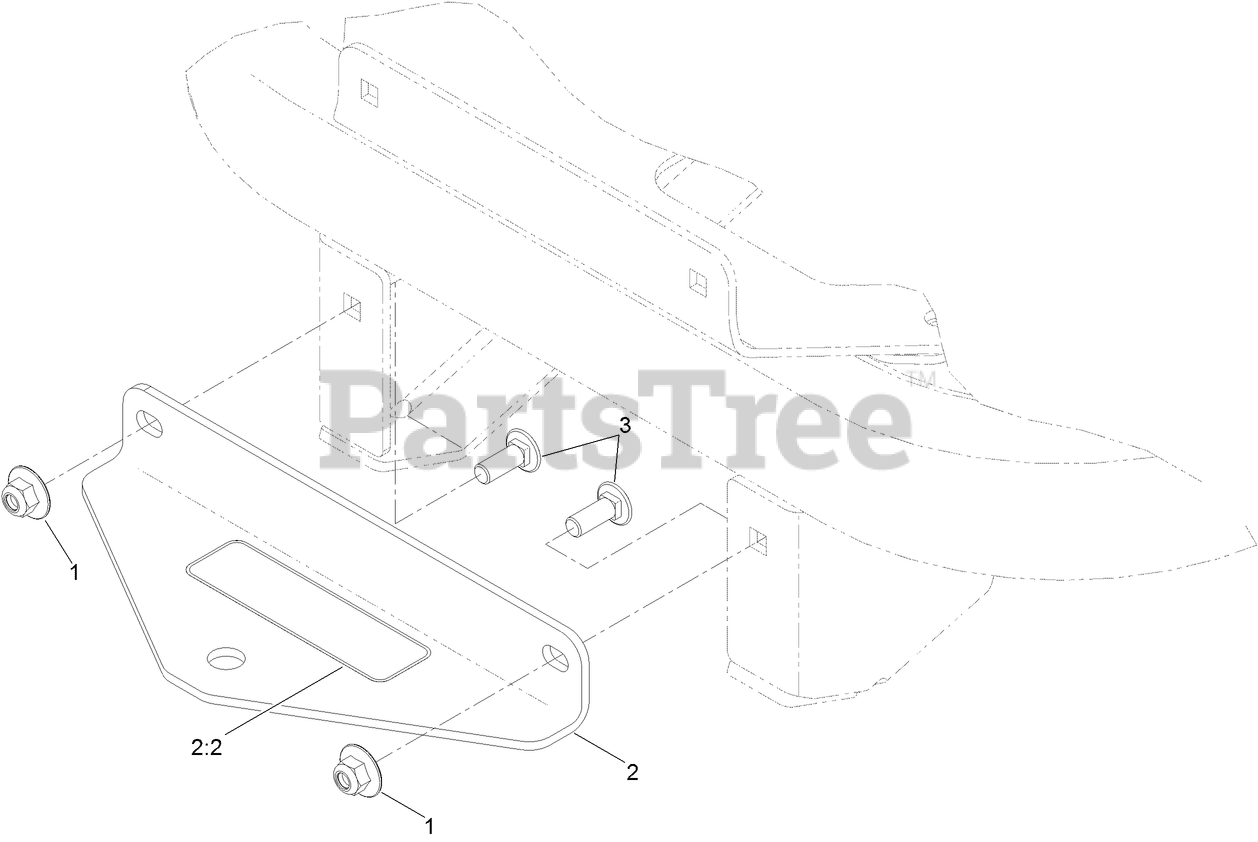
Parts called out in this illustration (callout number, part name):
1	NUT-FLANGE, NI
2	HITCH
2:2	DECAL-MAX DRAWBAR PULL
3	SCREW-CARR
